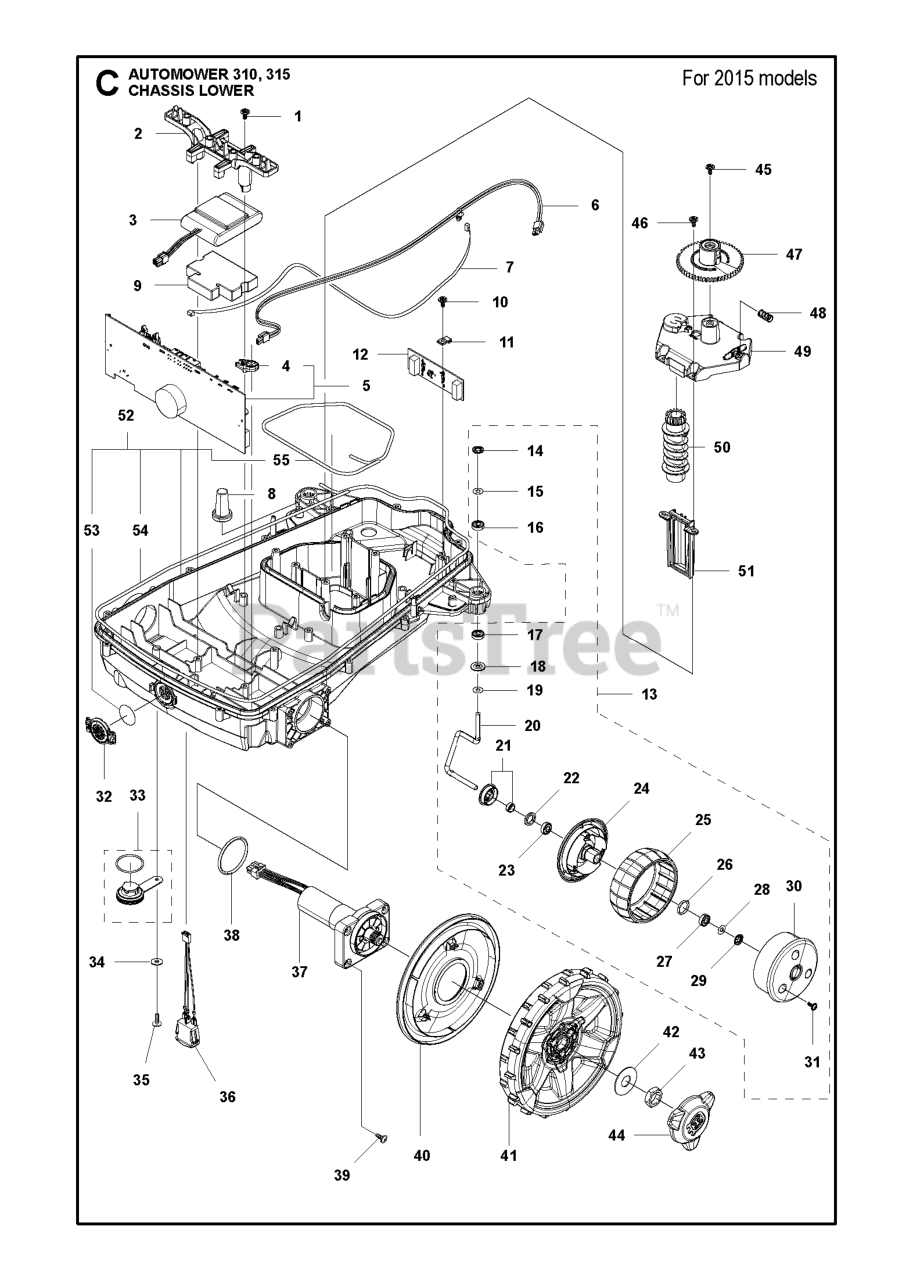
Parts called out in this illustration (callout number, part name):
1	SCREW ITXPANT
2	HOLDER BATTERY
3	BATTERY LI-ION
6	LOOM CHARGING LINK
7	LOOM LOOP SENSOR
8	COLUMN FRONT
9	WEIGHT CENTER
10	SCREW ITXPANT
12	PRINTED CIRCUIT ASSY LOOP SENS
13	WHEEL KIT FRONT
14	LOCKWASHER STARLOCK SS 6MM GEO
15	WASHER FRONT WHEEL 6MM
16	BALL BEARING SINGLE ROW S696
17	BALL BEARING SINGLE ROW S696
19	WASHER FRONT WHEEL 6MM
20	SPINDLE FRONT WHEEL 6 MM
21	SHIELD KIT
22	SEALING 12X18X3
23	BALL BEARING SINGLE ROW S696
24	WHEEL FRONT WHEEL INSIDE
25	WHEEL RUBBER TYRE
26	O-RING 2,62X15,54
27	BALL BEARING SINGLE ROW S696
28	WASHER FRONT WHEEL 6MM
29	LOCKWASHER STARLOCK SS 6MM GEO
30	WHEEL FRONT WHEEL OUTSIDE
31	SCREW 14MM
32	COVER AIR FILTER
35	SCREW ITXPANT
36	LOOM ON/ OFF
38	O-RING LIGHT GREY
39	SCREW ITXPANT
40	COVER REAR WHEEL
42	WASHER WASHER REAR WHEEL 16X40
43	HEXAGON THIN NUT
44	HUB CAP REAR WHEEL NO CENTER P
45	SCREW ITXPANT
46	SCREW ITXPANT
47	GEAR HEIGHT ADJUSTMENT
48	SPRING STOP BUTTON
49	COVER HEIGHT ADJUSTMENT PLASTI
50	SCREW HEIGHT ADJUSTMENT
51	RAIL HEIGHT ADJUSTMENT
52	CHASSIS LOWER
53	KIT AIR FILTER KIT 305 - 10 PC
54	SEALING STRIP P15 CHASSIS
55	SEALING STRIP P15 UPPER
